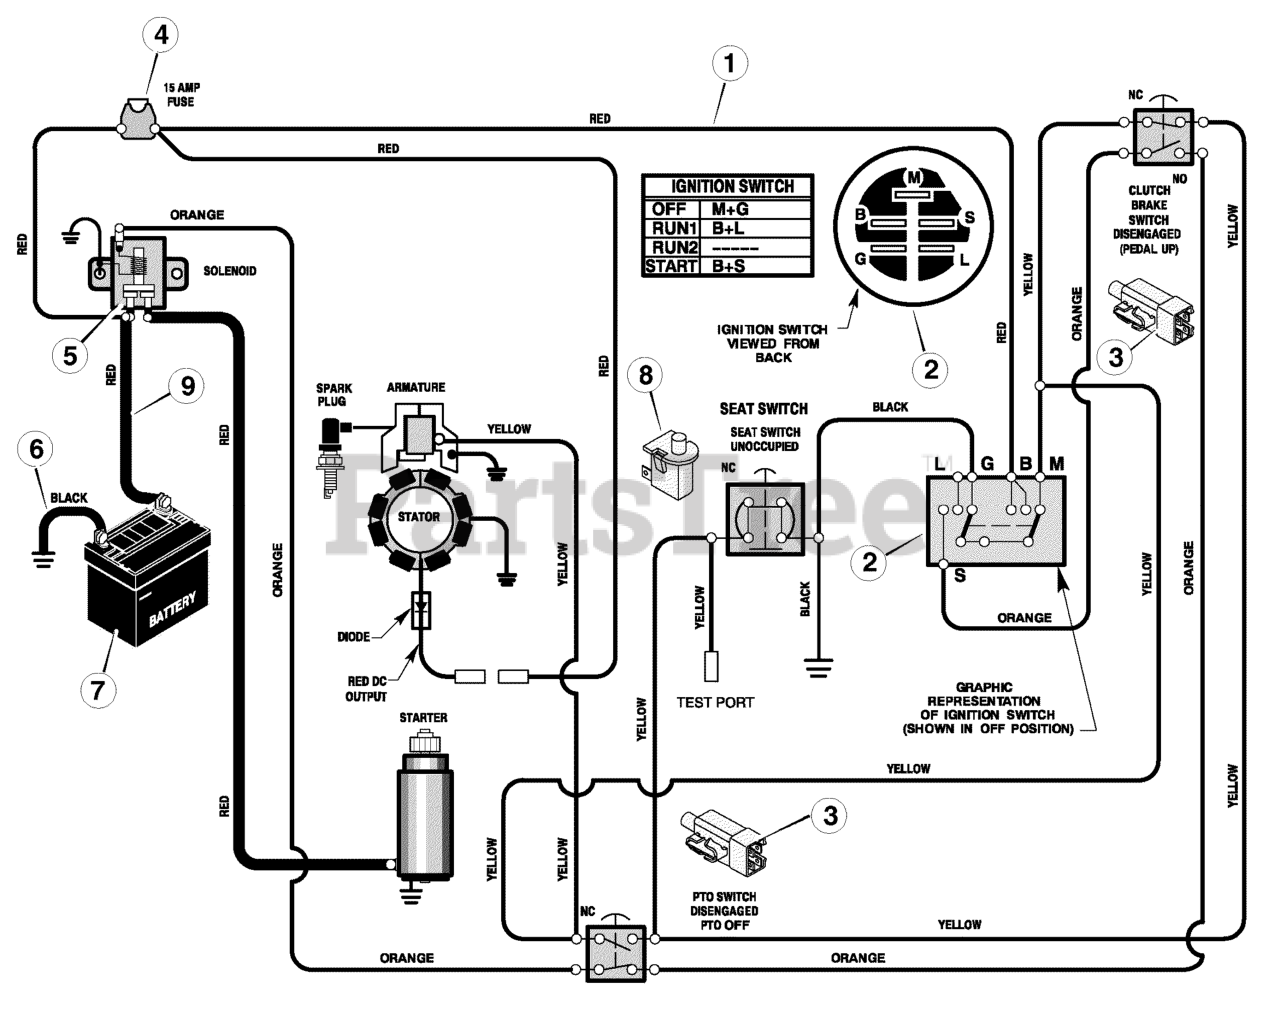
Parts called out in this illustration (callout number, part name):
1	Harness, Chassis Wire
2	Switch, Ignition
2	Key, Ignition
2	Nut, Hex
2	Cap, Ignition
3	Switch, Limit
4	Holder, Fuse
5	Solenoid
5	Screw, Mounting
5	Locknut
6	Cable, Battery Ground
6	Screw, Ground Cable
7	Battery
7	Bolt, Carriage
7	Wingnut
8	Switch, Seat Sensor
9	Cable, Red Batery
9	BOOT, Battery Terminal, Positive
